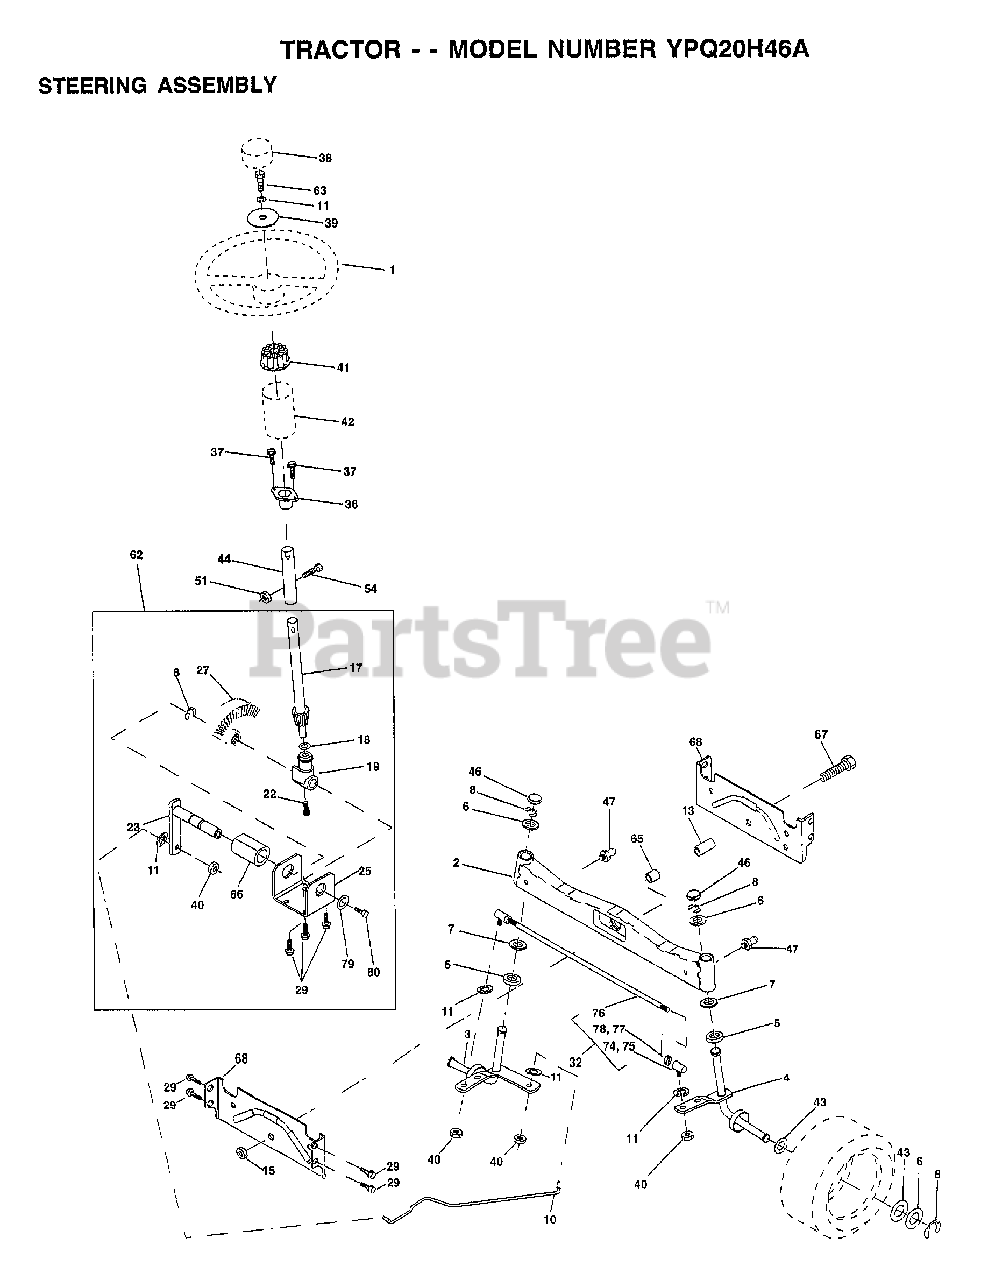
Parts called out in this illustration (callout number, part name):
3	"SPINDLE ASM,LH"
4	"SPINDLE ASM,RH"
5	WASHER .T
6	WASHER
7	WASHER
8	RING
10	LINK.DRAG
11	LOCKWASHER
13	BEARING.FRT.SPACER.AXLE
15	"NUT-LOC,FLANGE LT"
17	SHAFT ASM STEERIN
18	THRUST WASHER
19	SUPPORT.SHAFT.STEER
22	SCREW.HX.WSH.HD
23	SHAFT.ASM.PITMAN
25	BRKT-STEERING
27	GEAR SECTOR
29	SCREW
32	ROD.ASM.TIE.BALL
36	BUSHING.STEERING
37	"SCREW-TT,10-32 FL"
38	"INSERT,STR WHEEL"
39	WASHER
40	GRIPCO NUT
41	ADAPTER LT
42	BOOT.STEERING.DASH.P/L
43	WASHER
44	EXT SHAFT STEERIN
46	CAP
47	ZERK M
51	NUT
54	BOLT
62	KIT.STEER.ASM
63	BOLT
65	SPACER AXLE
66	"BEARING-ARM,PITMA"
67	BOLT
68	BRACE AXLE
74	JOINT.RH
75	JOINT.LH
77	NUT
78	NUT
79	WASHER
80	BOLT.HX.NYLON3/8-16X3/
